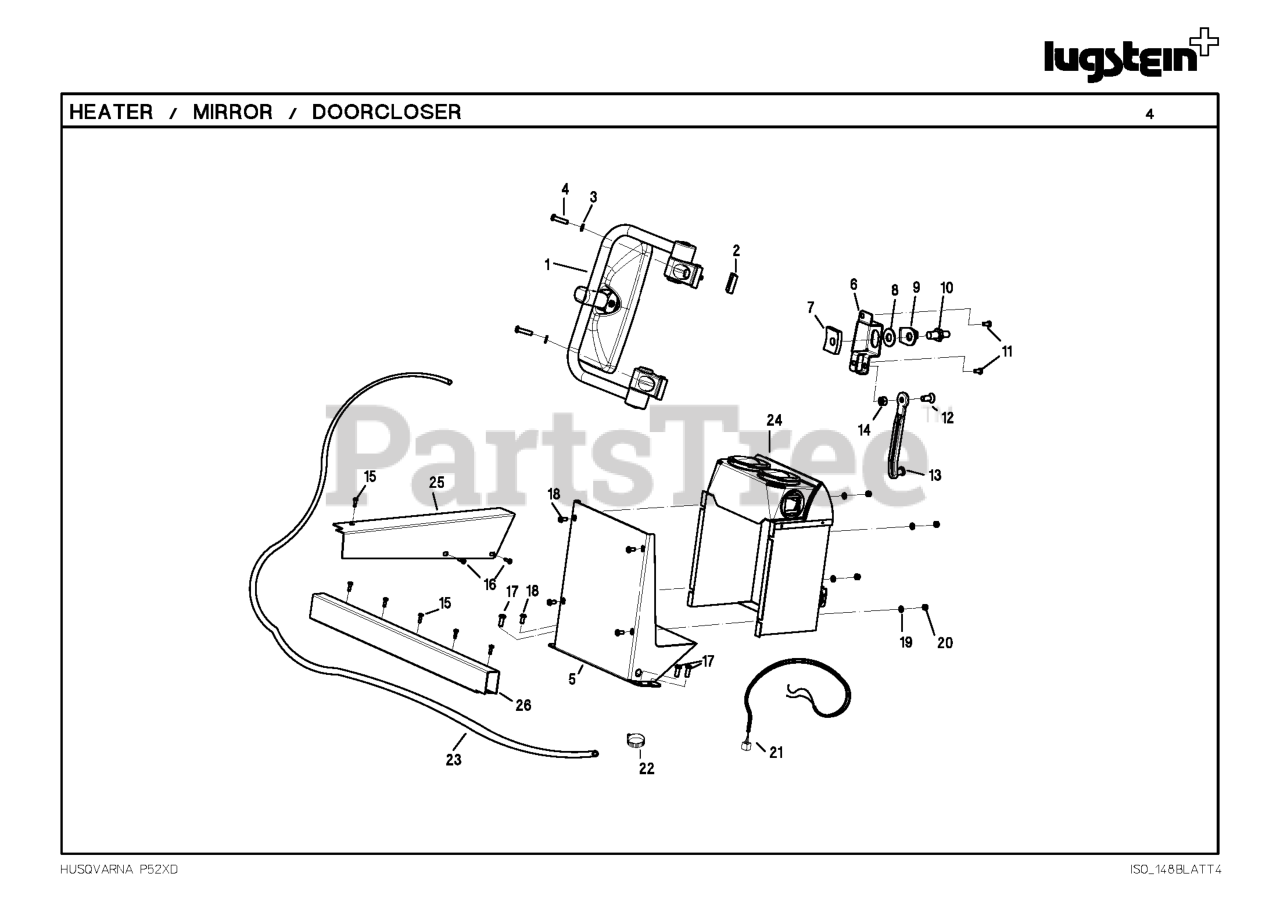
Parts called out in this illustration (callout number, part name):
14	LOCKNUT M8
19	WASHER
20	LOCKNUT M5
22	HOSE CLAMP FUEL HOSE
